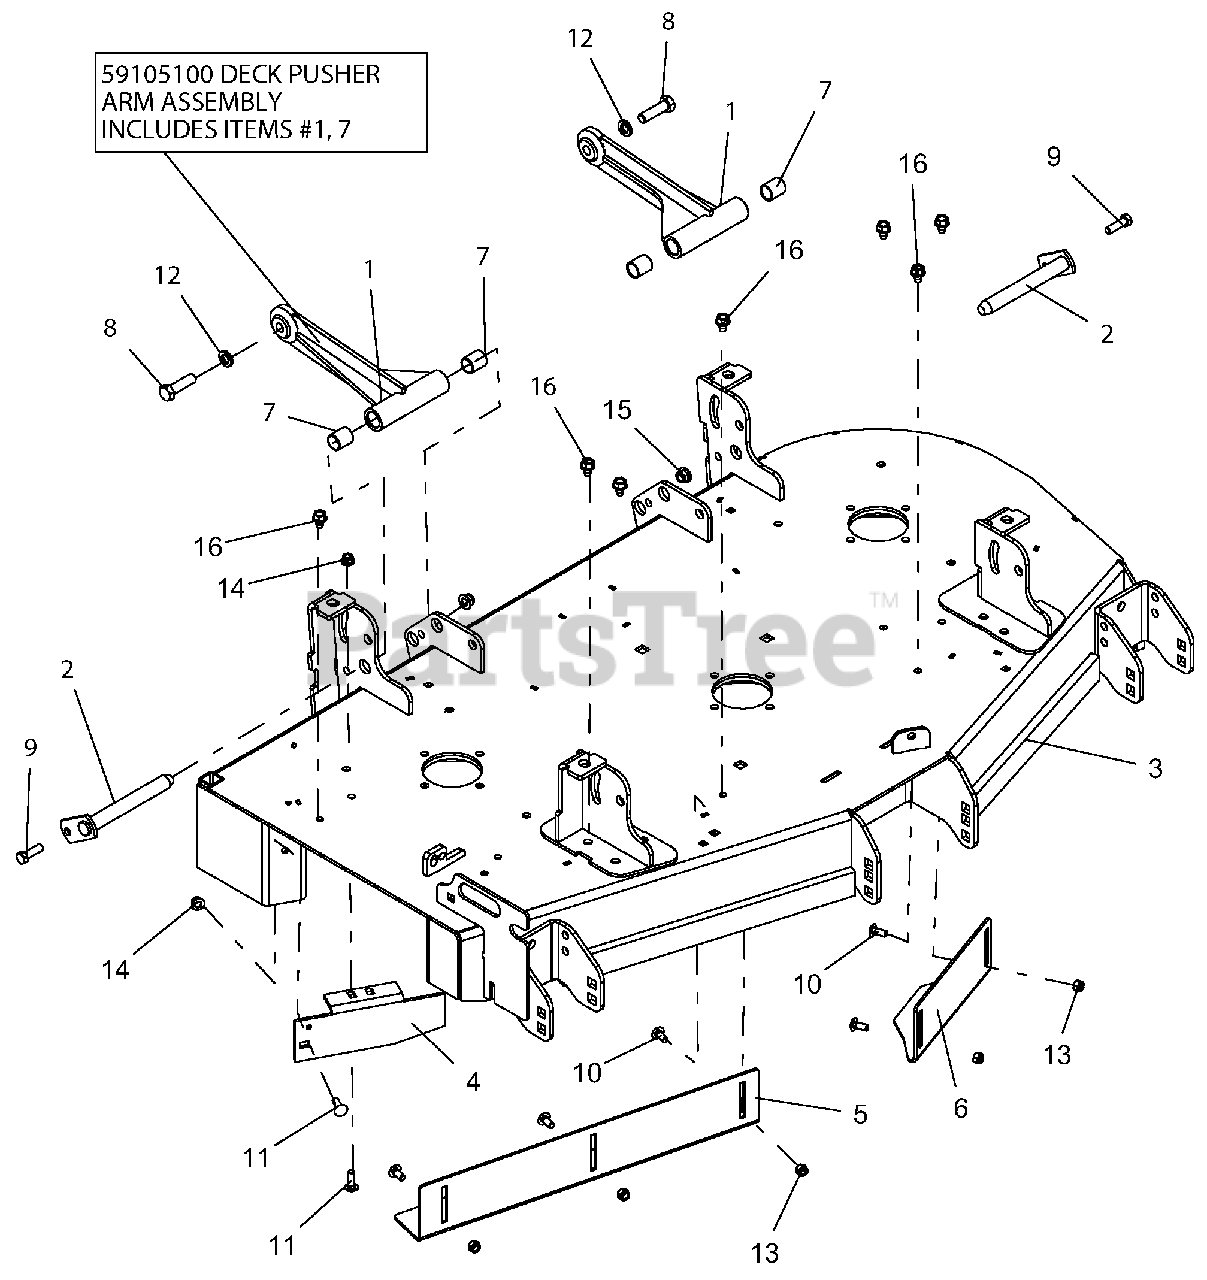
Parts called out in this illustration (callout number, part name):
1	WLDMT, DECK PUSHER ARM
2	WLDMT, MOWER MTG. PIN
3	KIT, PT148 MOWER DECK W/SAFETY DECALS-RED
4	BAFFLE, 44-48" SIDE DISCHARGE
5	BAFFLE, 48" RH VACUUM
6	BAFFLE, 44/48" LH VACUUM
7	BRG, .75 X .875 X 1.00
8	BLT-HEX .50-13X1.75 GR5 YWZC EP80
9	BLT-HEX .38-16X1.25 GR5 YWZC
10	BLT-RDHDSQNK .31-18X.75 G5 YWZC
11	BLT-RDHDSQSHNK .31-18X1.00 G5 Y
12	WSHR-LK .50X.125 REG YWZC
13	NUT-LK-NYL .312-18 YWZC
14	NUT-LK-NYL-FLG .31-18 YWZC
15	NUT-LK-NYL-FLG .38-16 YWZC
16	SCR-TAP .38-16X.50 HWH TR YWZ
